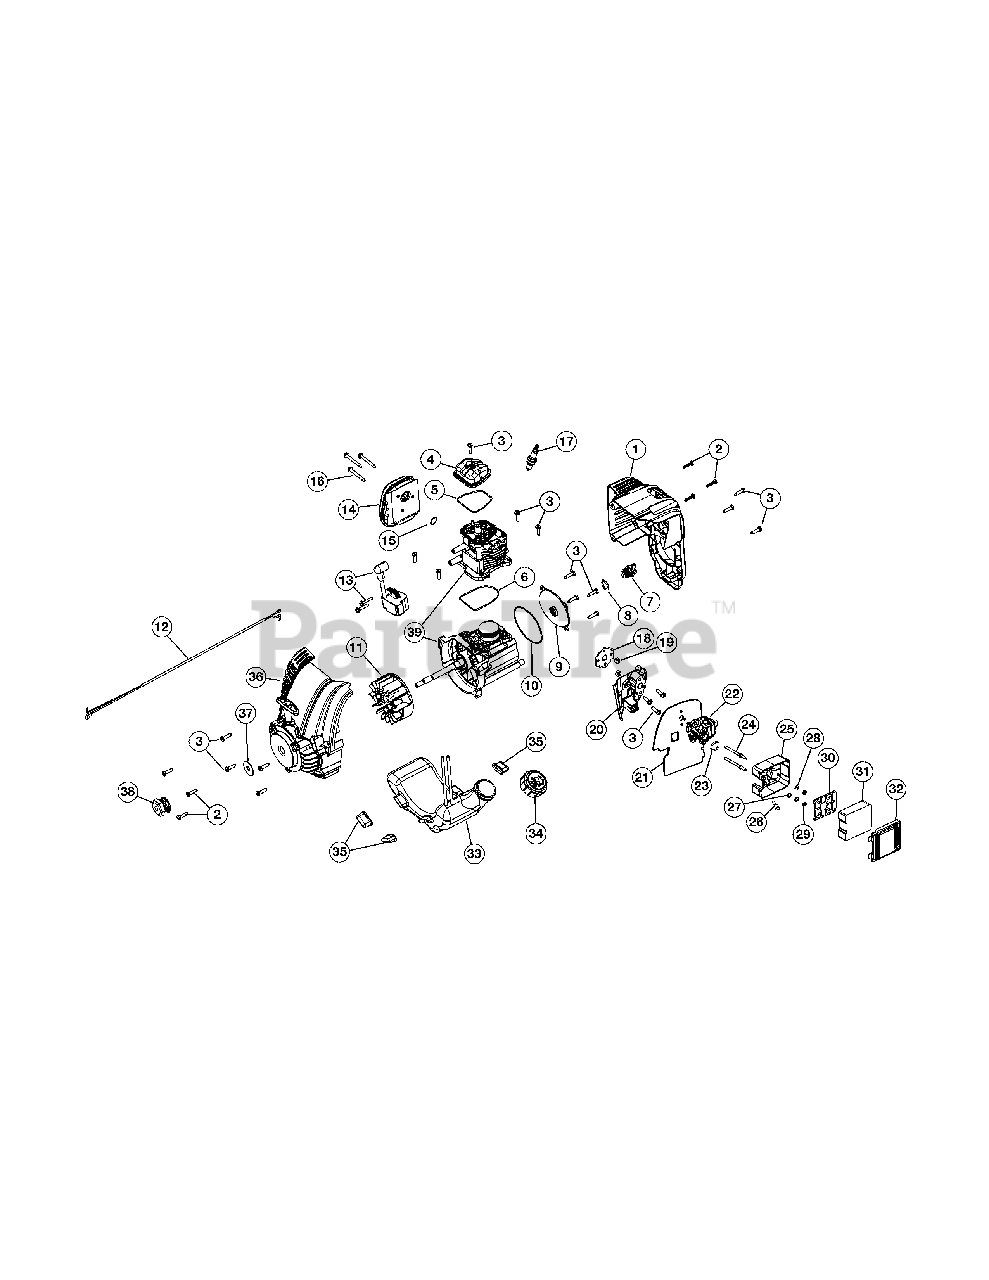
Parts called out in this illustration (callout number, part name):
1	Engine Cover Assembly (includes 2 & 3)
2	Cover Screw
3	Housing Screw
4	Rocker Cover
5	Rocker Cover O-Ring
6	Cylinder O-Ring
7	Oil Plug (includes 8)
8	Oil Plug O-Ring
9	Crankcase Cover
10	Crankcase Cover O-ring
11	Flywheel Assembly
12	Lead Wires
13	Module Assembly
14	Muffler Assembly (includes 15 & 16)
15	Muffler Gasket
16	Muffler Screw
17	Spark Plug
18	Insulator Gasket
20	Insulator (includes 21)
21	Carburetor Gasket
22	Carburetor Assembly
23	Carburetor O-Ring
24	Air Filter Mounting Screw
25	Air Cleaner Box Assembly
26	Breather Tube
27	Grommet Washer
30	Air Filter Plate
31	Air Filter
32	Air Filter Cover
33	Fuel Tank Assembly (includes 34)
35	Fuel Tank Pads
36	Starter Housing Assembly (includes 3)
38	Drive Shaft Pulley
39	Shortblock Asembly (includes 3-11, 13, & 17)
